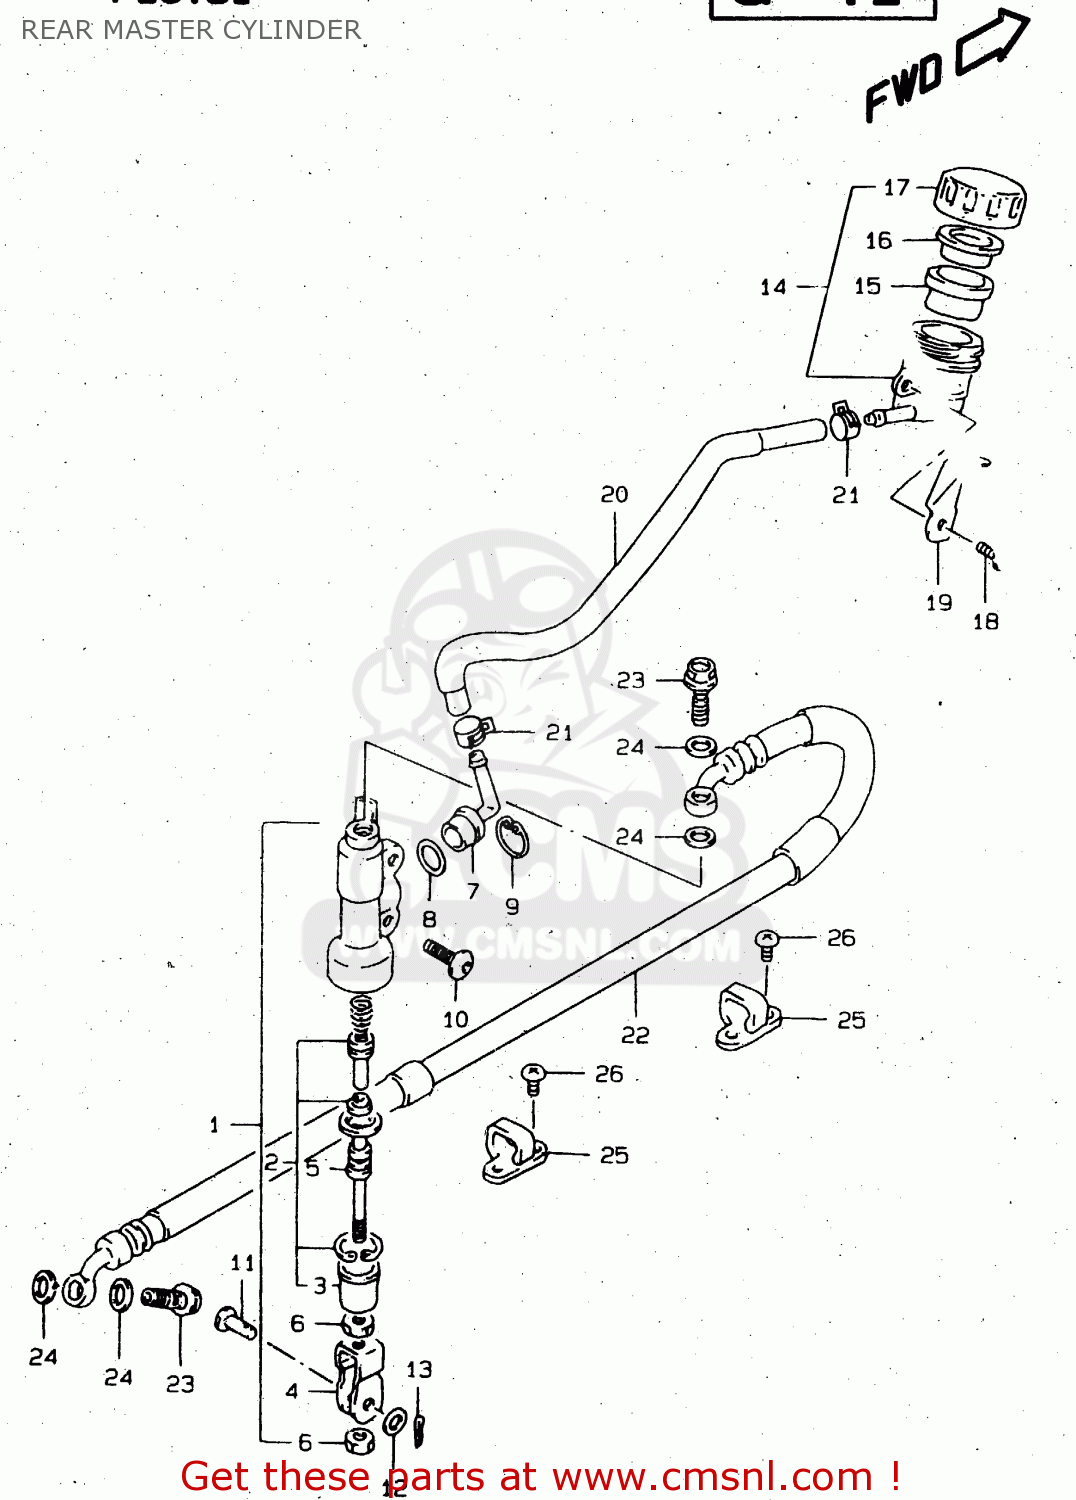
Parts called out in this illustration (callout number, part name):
1	CYLINDER ASSY,RR MASTER
2	PISTON/CUP SET
3	BOOT
4	YOKE
5	ROD,PUSH
6	NUT
7	CONNECTOR
8	O RING
9	CIRCLIP
10	SCREW(6X16)
11	PIN(8X20)
12	WASHER(8.5X13X1.6)
13	PIN 20X15
14	TANK ASSY,RR BRAKE RESERVOIR
15	DIAPHRAGM
16	PLATE
17	CAP
18	BOLT
19	GUARD,RSVR TANK CAP
20	HOSE,RESERVOIR TANK
21	CLIP
22	HOSE COMP,REAR BRAKE
23	BOLT UNION
24	WASHER(10X15X1.5)
25	GUIDE,RR BRAKE
26	SCREW
